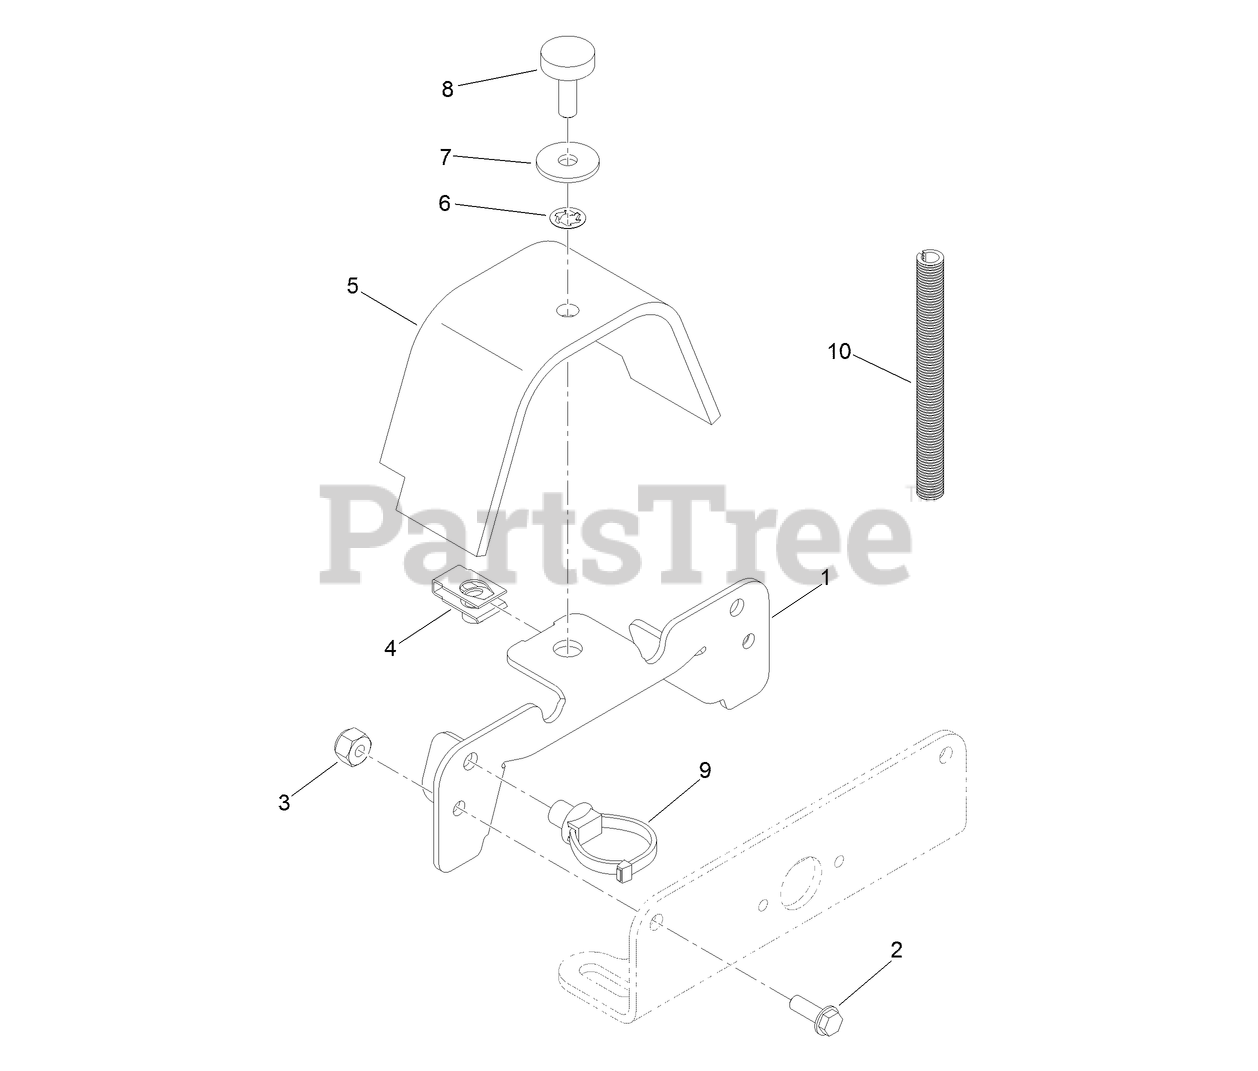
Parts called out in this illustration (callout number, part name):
1	BRACKET-ROTARY SENSOR, TOP
2	SCREW-HHF
3	NUT-LOCK, HH
5	COVER-RUBBER
6	NUT-RETAINING
7	WASHER
8	KNOB-SCREW, THUMB
9	CLIP-TIE
10	TUBE-SENSOR, ROTARY
